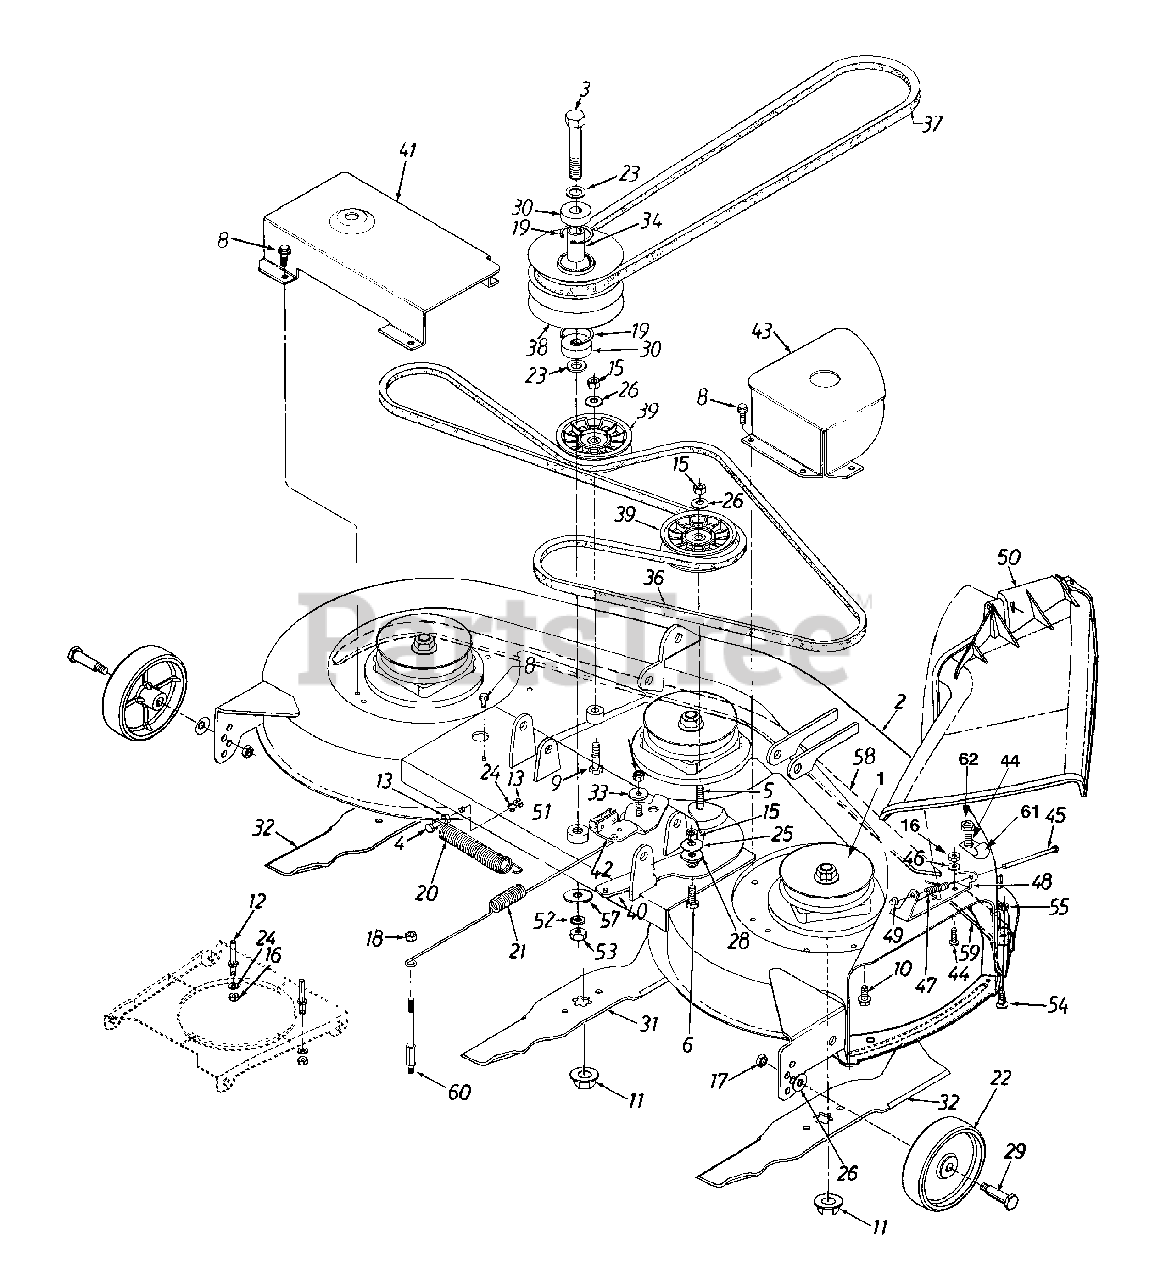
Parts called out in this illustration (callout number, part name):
1	Blade Spindle Ass'y.
4	Hex Bolt 1/4-28 x 1.25" Lg.
5	Hex Bolt 3/8-24 x 1.5" Lg.
6	Hex Bolt 3/8-24 x 1" Lg.
8	Hex Wash. Hd. TT-Tap Scr.
9	Hex Bolt 3/8-24 x 2" Lg.
10	Hex Flange Bolt 5/16-24 x .75"
11	Hex Flange L-Nut 5/8-18 Thd.
12	Belt Guard Pin
13	Hex Nut 1/4-28 Thd.
15	Hex Nut 3/8-24 Thd.
16	Hex Nut 1/4-20 Thd. (Gr. 5)
17	Hex Top Jam Nut 3/8-16 Thd.
18	Hex Center L-Nut 5/16-18 Thd.
19	Int. Snap Ring
20	Ext. Spring .88" O.D. x 6.17"
21	Ext. Spring .788" O.D. x 15.5"
22	Deck Wheel
23	Fl-Wash. .635" I.D. x 1" O.D.
24	L-Wash. 1/4" I.D.
25	Bell-Wash. 3/8" x 1.125" x .062"
26	Bell-Wash. 3/8" x .87" x .064"
28	Shoulder Spacer .625" I.D.
29	Shld. Bolt .498" x 1.525"
30	Ball Brg. .625" I.D. x 1.574" O.D.
31	Blade 14.88" Lg.
32	Blade 16.28" Lg.
33	Shoulder Spacer
34	Spacer .635" I.D. x .088" O.D.
36	V-Belt
37	V-Belt
38	Pulley Double Deck 5" O.D.
39	Flat Idler Pulley 3.5 O.D.
44	Hex Bolt 1/4-20 x .62" Lg.
45	Hinge Pin
46	Bell-Wash. 1/4" I.D.
47	Torsion Spring
48	Hinge Mtg. Brkt.
49	Push Nut
50	Chute Ass'y. Comp.
51	Spacer .635" I.D. x 1" O.D.
52	L-Wash. 5/8" I.D.
53	Hex Nut 5/8-18 Thd.
54	Carriage Bolt 1/4-20 x .5" Lg.
55	Hex Sems Nut 1/4-20 Thd.
57	Fl-Wash. .635" I.D.
60	Return Spring Stud
61	Retainer Hook Bracket
62	Hex Lock Nut 1/4-20
